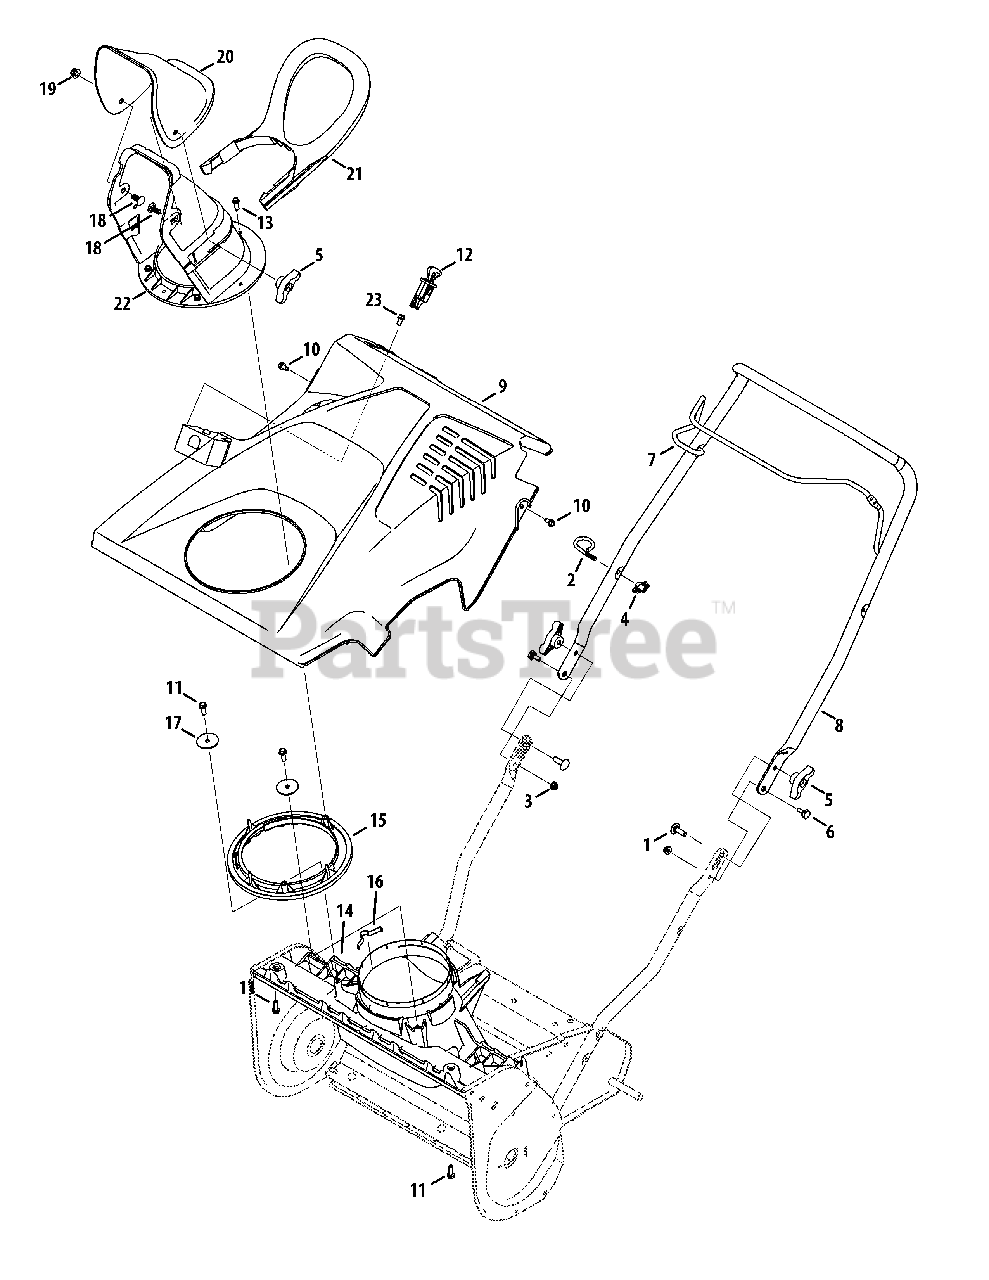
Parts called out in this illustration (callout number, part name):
1	Carriage Bolt, 5/16-18 x 1.00
2	Eye Bolt, 1/4-20
3	Flange Lock Nut, 1/4-20
4	Knob Handle
5	Wing Knob
6	Shoulder Screw, .375 x .148 x 1/4-20
7	Auger Bail
8	Upper Handle
9	Top Cover (Black w/o electric start)
10	Hex Washer Screw, 1/4-20 x .625
11	Screw, Hi-Lo:1/4-15, 0.75
12	Ignition Switch Assembly
13	Hex Washer Screw, 1/4 x .750
14	Chute Adapter
15	Chute Ring
16	Chute Adjustment Spring
17	Flat Washer, .28 x 1.5 x .066
18	Carriage Bolt, 5/16-18 x .750
19	Flange Lock Nut, 5/16-18
20	Upper Chute
21	Chute Handle
22	Lower Chute
23	Hex Washer Screw, 1/4-15 x .50
